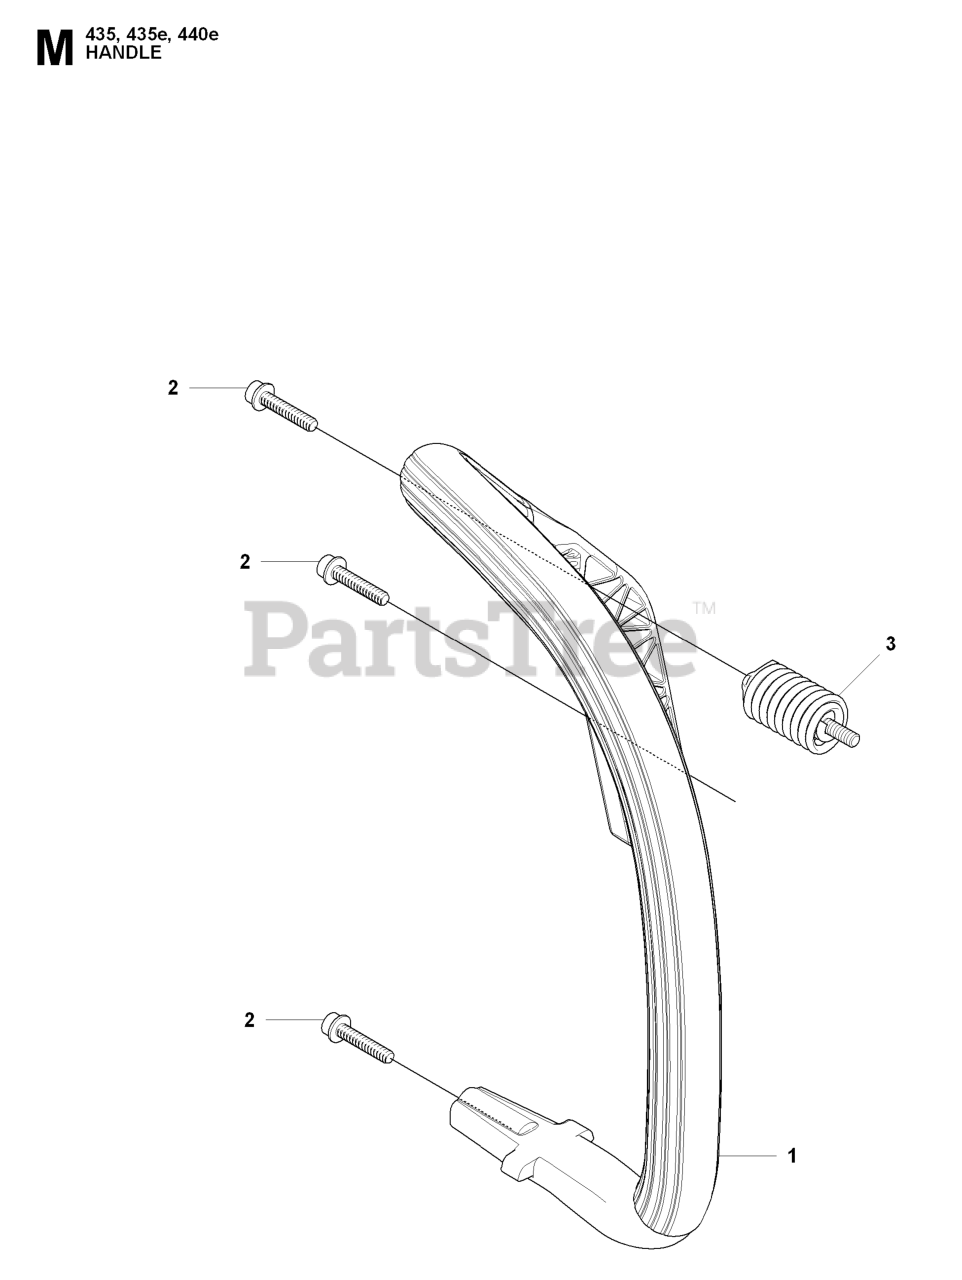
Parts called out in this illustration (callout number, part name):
1	FRONT HANDLE
2	SCREW
3	INSULATOR
